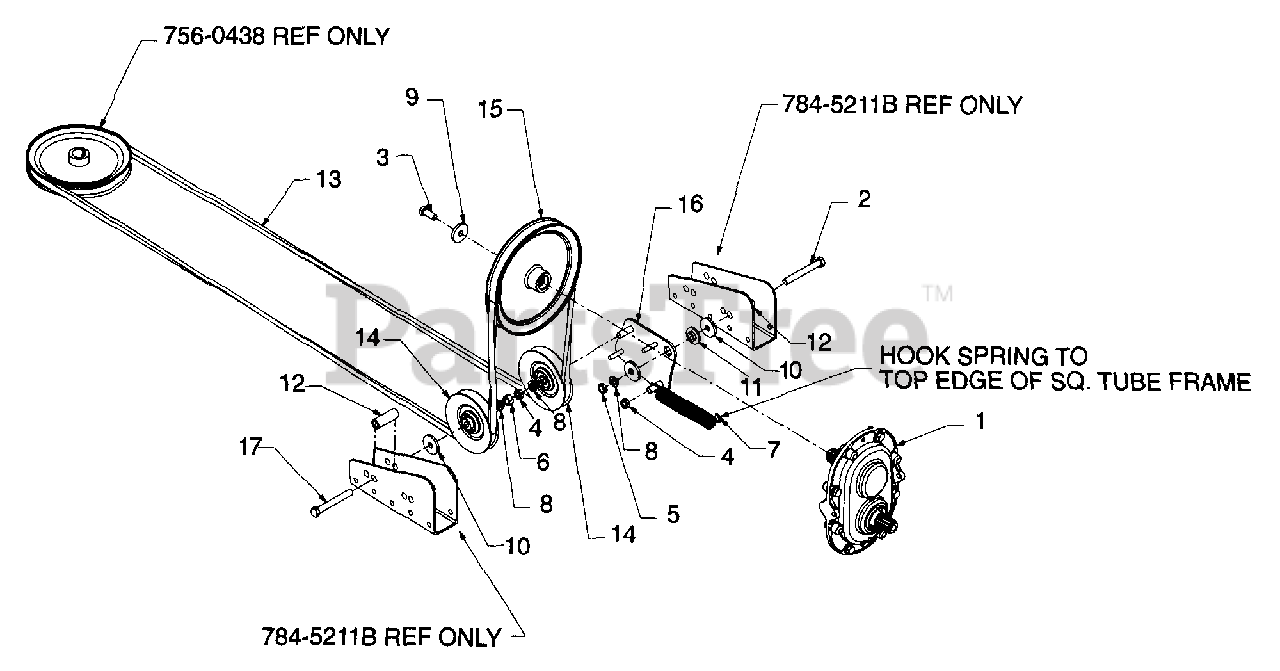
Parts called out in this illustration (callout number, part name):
1	Box Asm:Spkt.
2	HHCS:3/8-16:3.00:Gr8:Std.
3	HHCS:3/8-24:.875:Gr8:Std.
4	Nut:Jam:3/8-24:Ins Lock
5	Hex Cent L-Jam Nut 3/8-16
6	Hx. Nut:3/8-16:Gr B:
7	Spring:Extn:.87 Dia. x 6.00 Lg.
8	Wash:Lock:3/8:Regular Dh
9	Flat Wash..406 I.D. x 1.25 O.D.
10	Flat Wash..406 I.D. x 1 1/4 O.D.
11	Shld Spacer .625 I.D. x .169
12	Spacer .32 I.D. x .625 O.D. x 1.74
13	Belt:V Typ:A Sect. x 126.0 Poly
14	V-Belt Idler-.38 I.D. x 4.0 Dia.
15	Pulley:Dr.:7.00 Dia.
756-0438	Pulley
784-5211B	Bracket-Idler Sup
